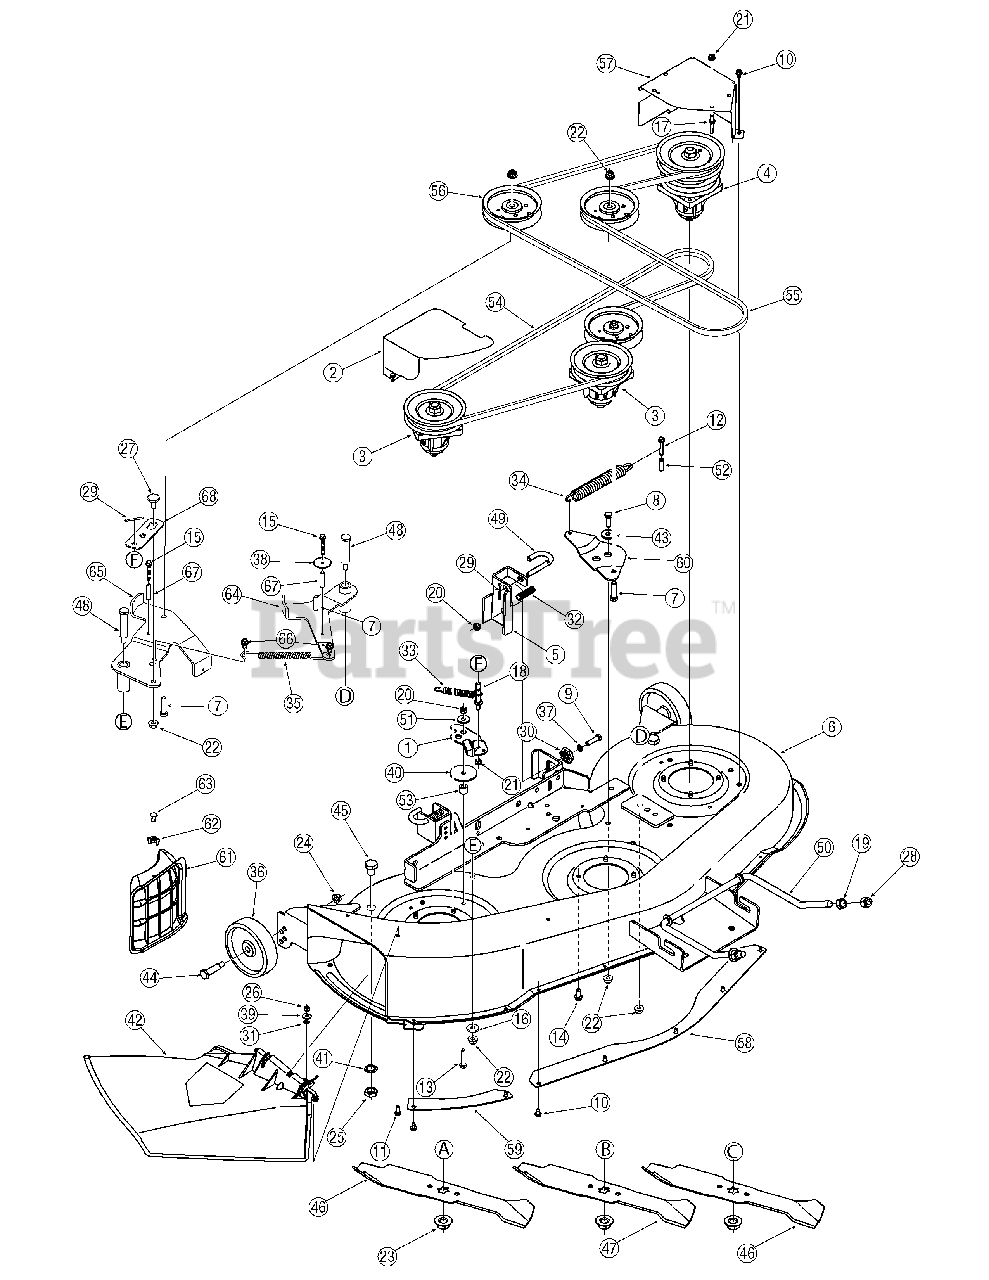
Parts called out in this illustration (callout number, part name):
1	Brake Assembly, Deck
3	Spindle Assembly, 5.00 Dia.
4	Spindle Ass’y, Double Pulley
7	Screw, 3/8-16, 1.50, Gr5
8	Screw, 3/8-16, 1.00, Gr5
9	Screw, 5/16-18, 1.25, Gr5
10	Screw, 1/4-20, 0.500
11	Screw, 1/4-20, .75, Gr5
12	Screw, 1/4-20, 1.500
13	Screw, 5/16-18, 1.50, Gr5
14	Screw, Ld, 5/16-18, 0.750
15	Screw, 1/4-20 x 1.75
16	Washer, Flat, .406 x 1.25 x .157
17	Belt Guard Pin 1/4 Dia x 1.43
18	Pin, 1/4-20, 3/8 x 2.0
19	Nut, Hex, 1/2-13, Gr5
20	Nut, Flange Lock, 5/16-18, GrF
21	Nut, Flange Lock, 1/4-20, GrF
22	Nut, Flange Lock, 3/8-16, GrF
23	Nut, Flange, 5/8-18
24	Nut, Flange Lock, 3/8-16, GrF
25	Nut, Hex, M16-1.5
26	Nut, Hex, 1/4-20, Gr5
27	Shld, Screw, .625 Dia. x .217
28	Nut, Hex Lock, 1/2-13, Gr8, Nylon
29	Pin, Cot, 1/8 x 1.25
30	Adjustment Gear, Deck
31	Nut, Push, .25 ID x .50 OD
32	Sprg, Compress, .531 OD x 1.75
33	Spring, Extension, .50 Dia x 3.97
34	Spring, Extension, .91 Dia x 7.33
35	Spring, Extension, .75 OD x 6.75
36	Wheel, Deck 5.0 x 1.38
37	Washer, Lock, 5/16
38	Washer, Flat, .285 x 1.25 x .06
39	Washer, Bell, .265 x.75 x . .062
40	Washer, Flat, .34 x 2.25 x .10
41	Washer, Lock, 5/8
42	Chute Assembly
43	Spacer, Shoulder, .625 ID x .169
44	Spacer, Shoulder, .498 x 1.53
46	Blade, 16.28", Star 3-in-One
47	Blade, 14.88", Star 3-in-One
48	Shld. Screw, .625 x 2.515 x .875
49	Rod, Deck Release
50	Rod, Deck Adjustment
51	Shoulder Spacer
52	Spacer, .260 x .372 x 1.030
53	Spacer, .375 x .63 x .595
54	Belt, V-Type, Poly, A x 79.10
55	Belt, V-Type, A x 90.24
56	Pulley, Idler, 4.25" Dia.
62	Wing Nut (if equipped)
63	Carriage Screw, 1/4-20 x .62 (if equipped)
67	Spacer, .260 x .372 x 1.420
